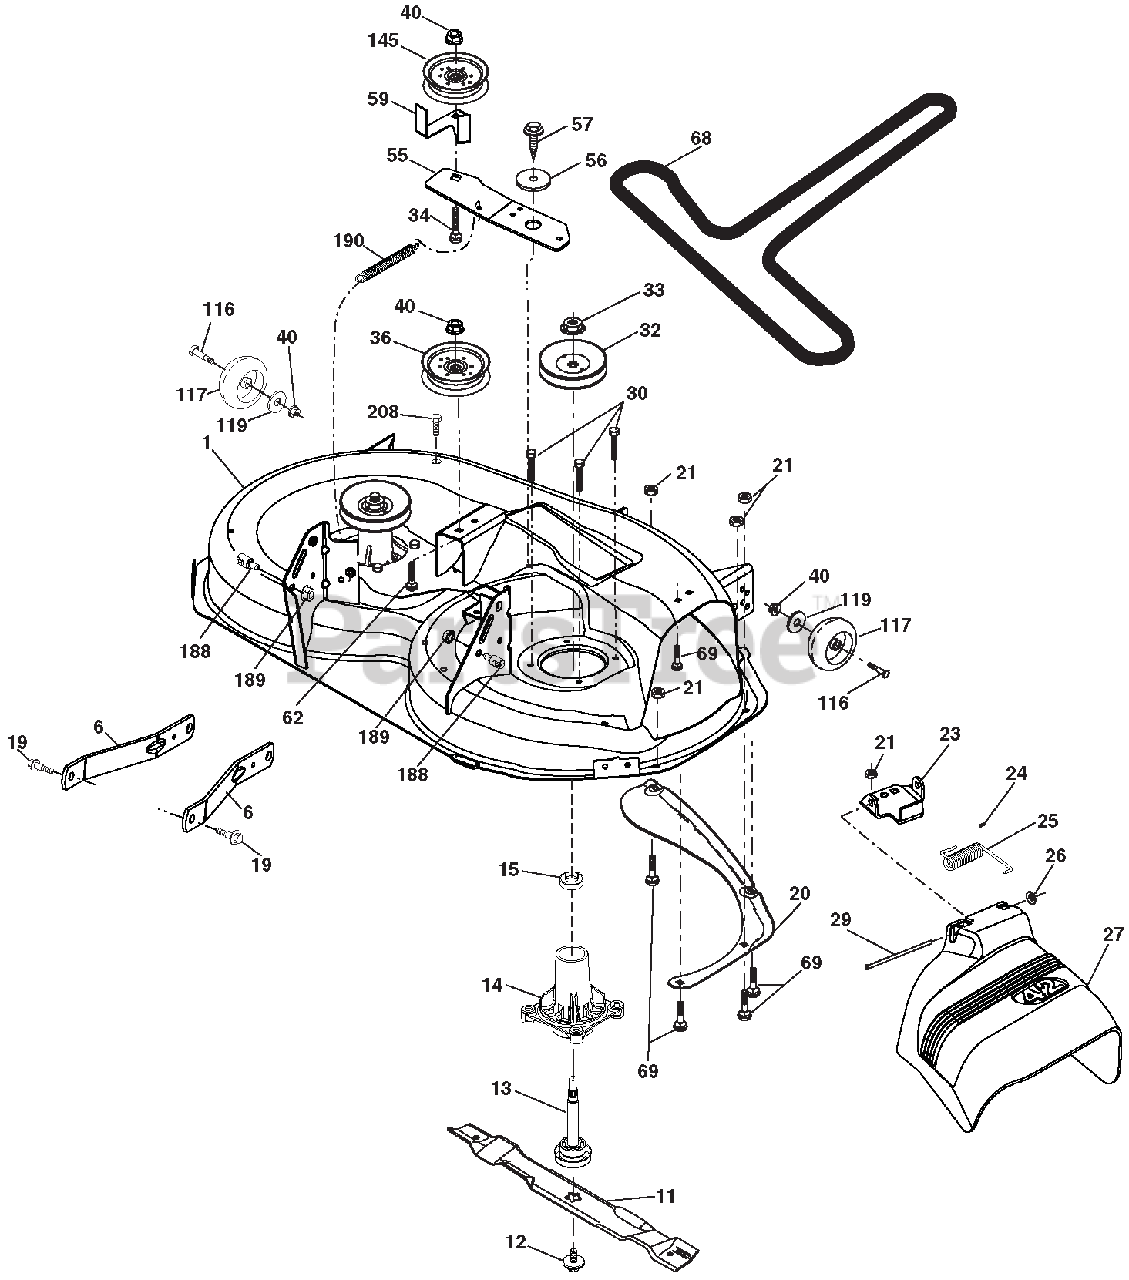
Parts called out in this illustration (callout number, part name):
1	MOWER HOUSING
6	ARM.SUSPENSION.MOWER.REAR.LD
11	BLADE.MOWER.42"HI LIFT PREMIUM
12	SCREW 7/16-20 X 1
13	SHAFT ASM
14	HOUSING.MANDREL.4PT.SERVICE
15	BEARING
19	BOLT.SHOULDER
20	BAFFLE.VORTEX.42.STD/HEAVY DTY
21	Nut, Hex, Crownlock 5/16-18
23	BRACKET.DEFLECTOR.38/42"2005
24	CAP.SLEEVE..80X.112.BLK.MOWER
25	SPRING.TORSION.DFL.38/42/46.GR
26	NUT.PUSH.PHOS.& OIL
27	SHIELD.DEFLECTOR.
29	ROD.HINGE.42/46"
30	SCREW.THD ROLL.DOD PT.HEX
32	MANDREL.PULLEYS.42,44,50
32	MANDREL ASM
33	NUT.FLANGE.LOCK.TOP
34	BOLT.CARR.SH.3/8-16X1-1/2.GR5
36	PULLEY.IDLER.4.50.RAW
40	Nut, Hex, Flangelock 3/8-16
55	IDLER.ARM
56	SPACER.RETAINER
57	SCREW.3/8-16X1.SMGML.TAP/R.BLK
59	GUARD.TUV.IDLER
62	BOLT.RD.HD.SQ.NK.3/8-16UNC X 2
68	V-Belt, 42" Mower
69	BOLT.RDHD.SQNK.5/16-18 X 5/8
116	BOLD SHLD "A" 2.41 "B" 1.66
117	WHEEL.GAGE.HALF.SPOKED
119	Washer 3/8 x 7/8 x 14 Ga.
145	PULLEY.IDLER 48"PRIMARY
188	STUD.FASTNER.W/'D'ANTI-ROTATIO
189	Nut, Lock Hex Flange 5/16-18 u
208	SCREW.THDROL.3/8-16X1/2.TYT.BL
